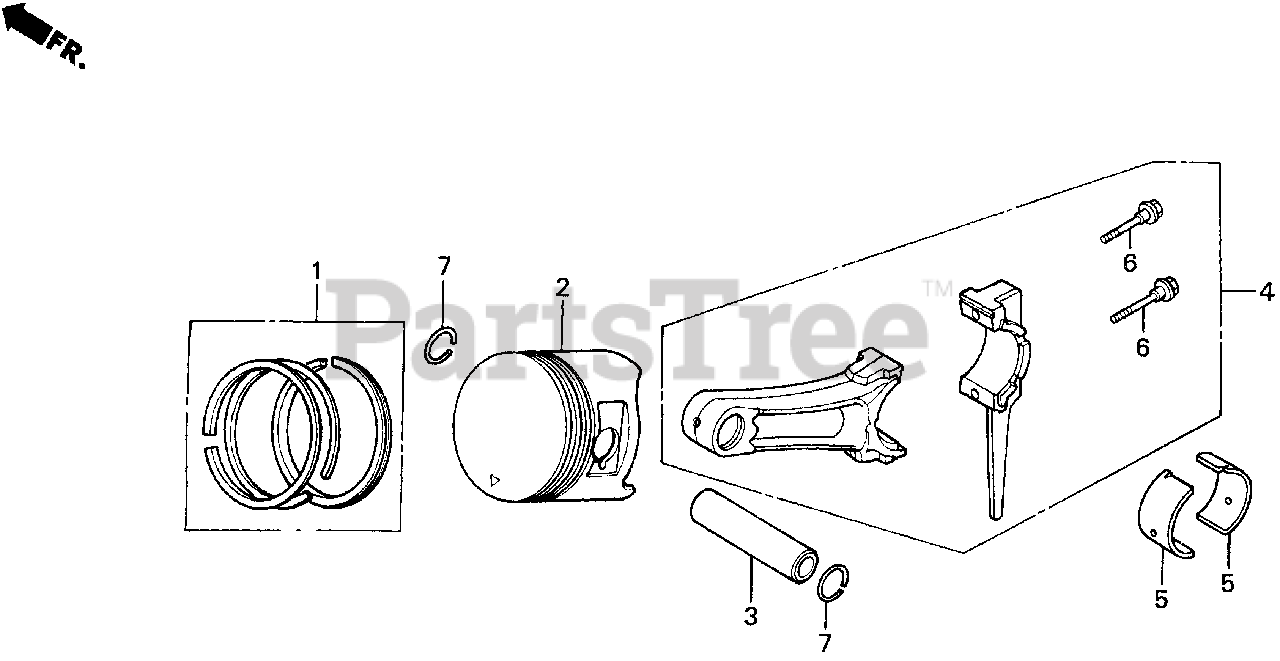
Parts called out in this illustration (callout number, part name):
1	RING SET, PISTON (STD) (NIPPON)
1	RING SET, PISTON (OS 0.25)
1	RING SET, PISTON (OS 0.50)
2	PISTON (STD)
2	PISTON (OS 0.25)
2	PISTON (OS 0.50)
2	PISTON (OS 0.75)
3	PIN, PISTON
4	ROD ASSY., CONNECTING (STD)
4	ROD ASSY., CONNECTING (0.25 LOWER SIZE)
6	BOLT, CONNECTING ROD
7	CLIP, PISTON PIN (20MM)
